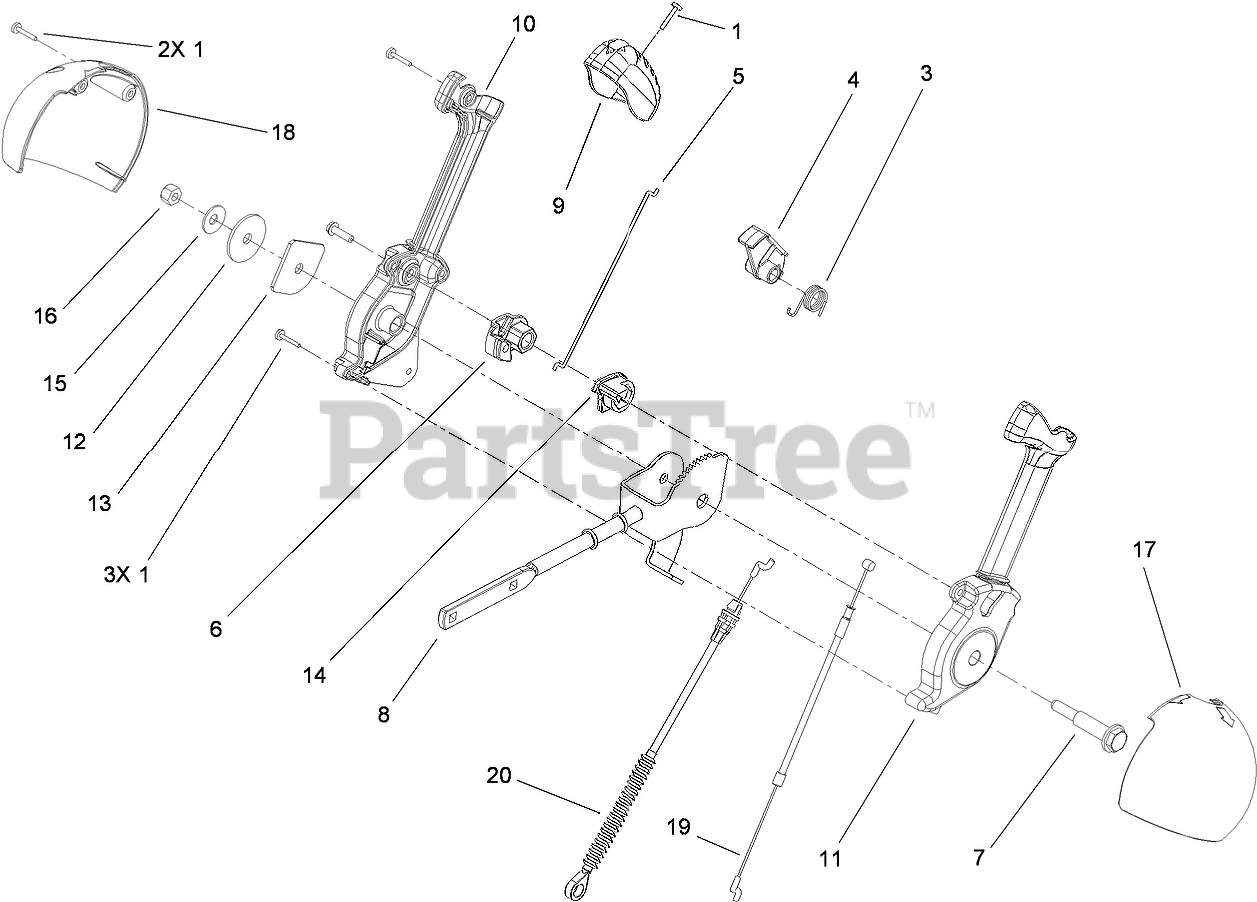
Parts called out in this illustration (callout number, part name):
1	SCREW-PPH
3	SPRING-TORSION
4	TRIGGER-LATCH
5	LINK-LATCH
6	LEVER-CABLE, DEFLECTOR
7	SCREW-SHOULDER
8	ROD-CONTROL, CHUTE
9	CAP-LEVER
10	LEVER-CONTROL, CHUTE (RH)
11	LEVER-CONTROL, CHUTE (LH)
12	WASHER-NYLON
13	PLATE-FRICTION
14	PAWL-LATCH
15	WASHER-BELLEVILLE
16	NUT-LOCK, NI
17	COVER-LEVER, CHUTE (LH)
18	COVER-LEVER, CHUTE (RH)
19	CABLE-RELEASE, CHUTE
20	CABLE-CONTROL, DEFLECTOR
